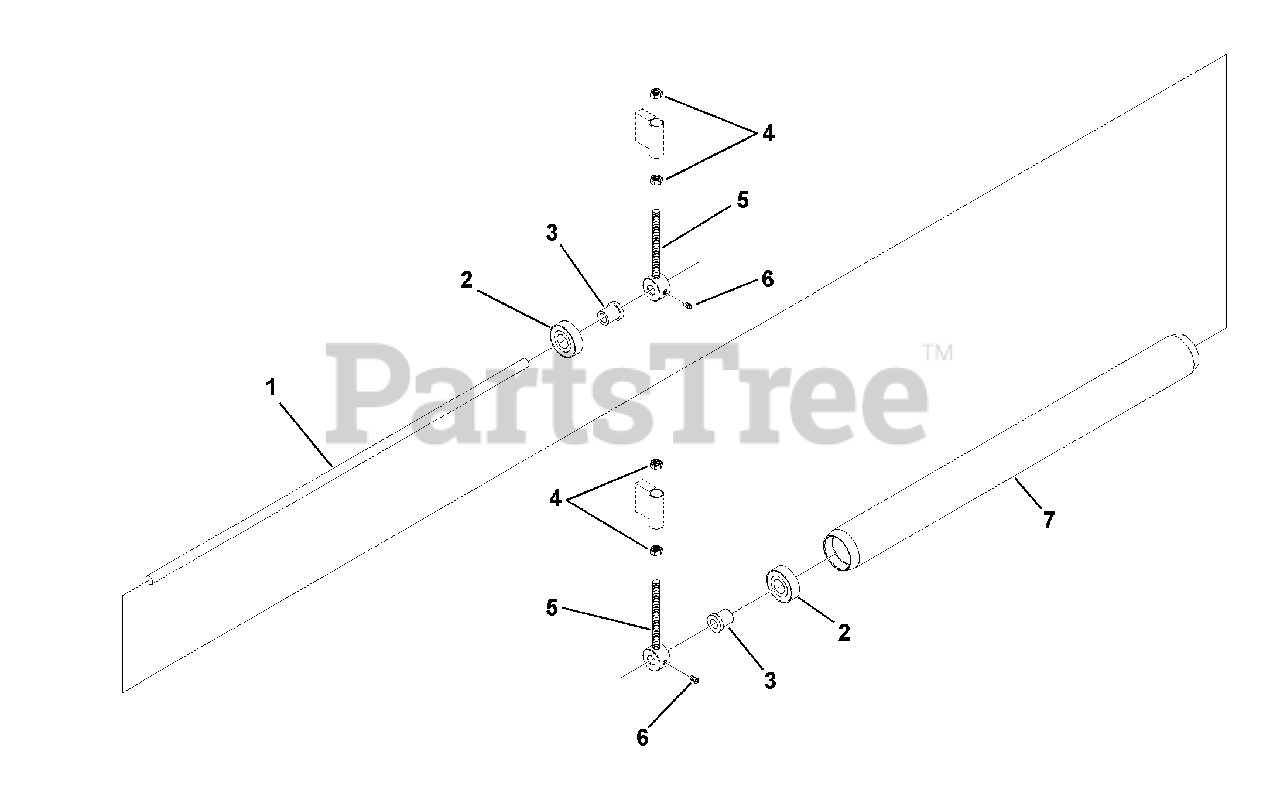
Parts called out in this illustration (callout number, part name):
1	Shaft, Front Roller 25-Inch (995030, 032)
2	Bearing, 47 mm x 20 mm x 14 mm
4	Nut, Jam .50-13
5	Weldment, Front Roller Adjustment Rod
6	Set Screw, Square Head Cup Point .25 x .50
7	Roller, Height 25-Inch (995030, 032)
